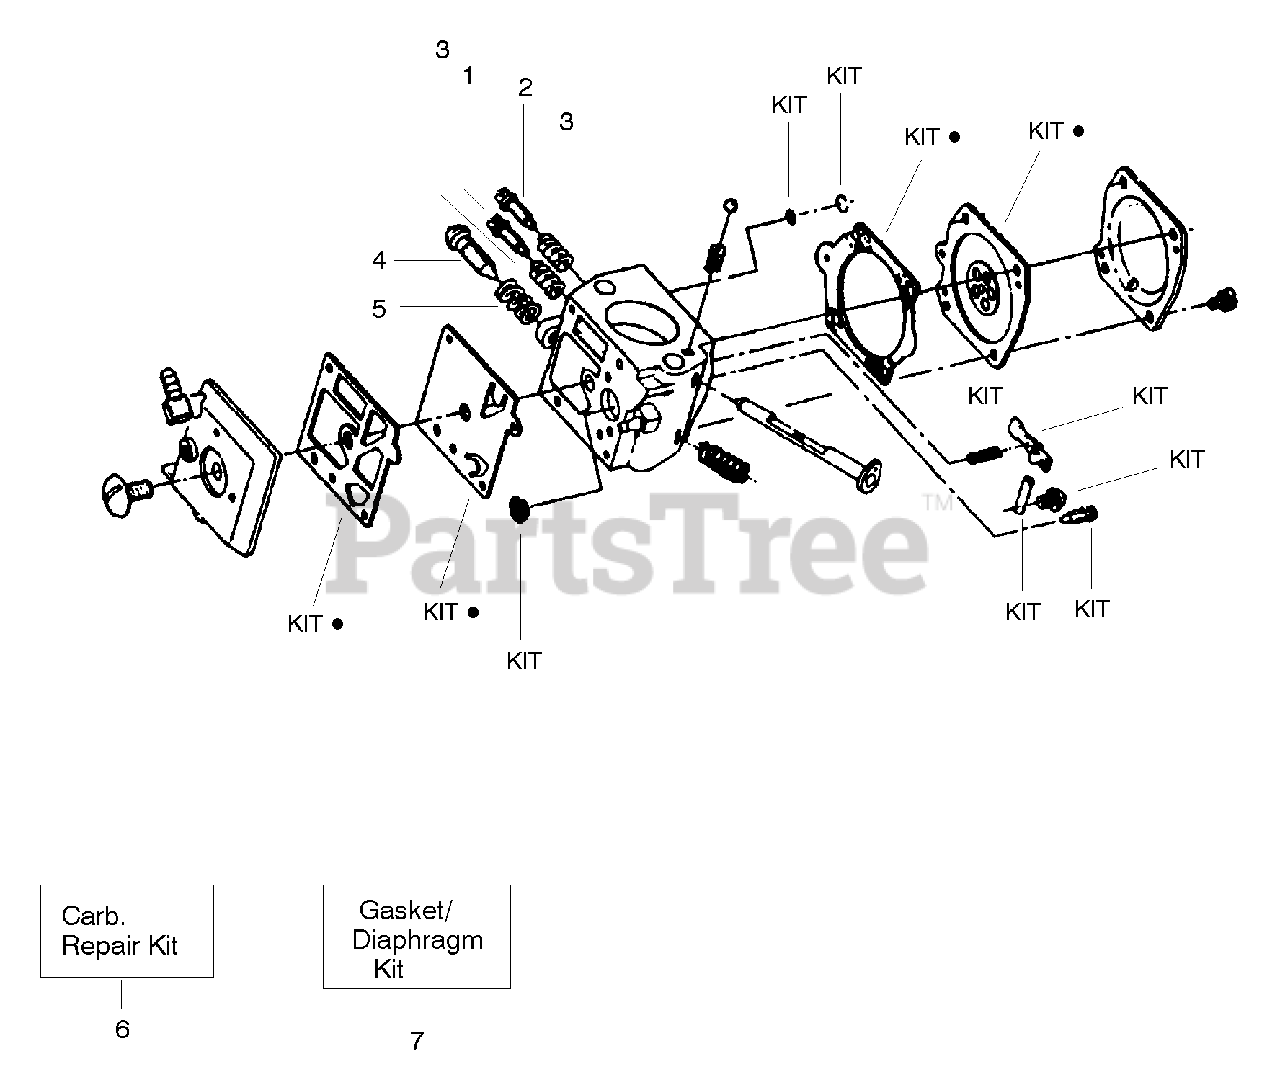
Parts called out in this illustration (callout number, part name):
1	Needle (Low)
2	Needle (High)
3	Needle Adjust Spring
4	Idle Adjust Screw
5	Idle Adjust Spring
6	Carburetor Repair Kit
7	Gasket/Diaphragm Kit
